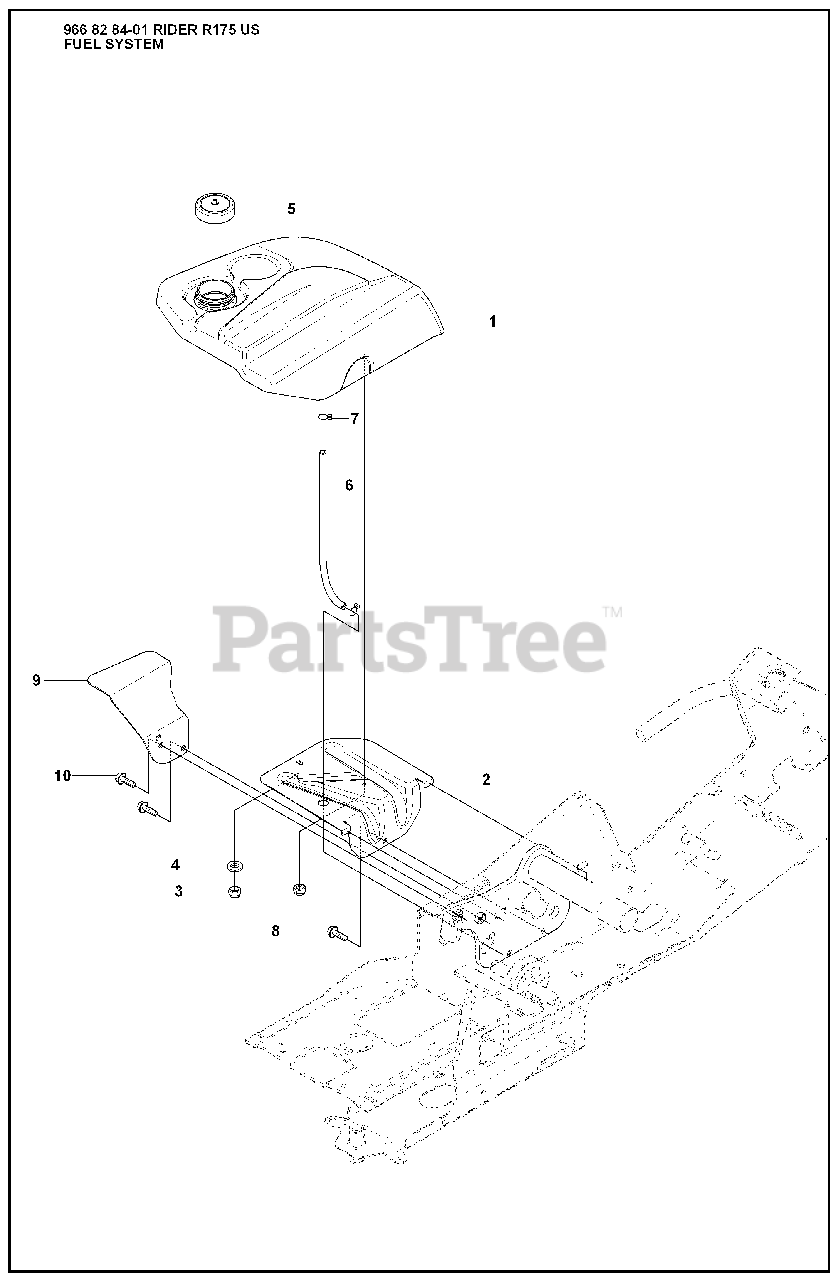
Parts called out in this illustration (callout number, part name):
3	LOCKNUT M6
4	WASHER
10	Screw, M10 X 25
